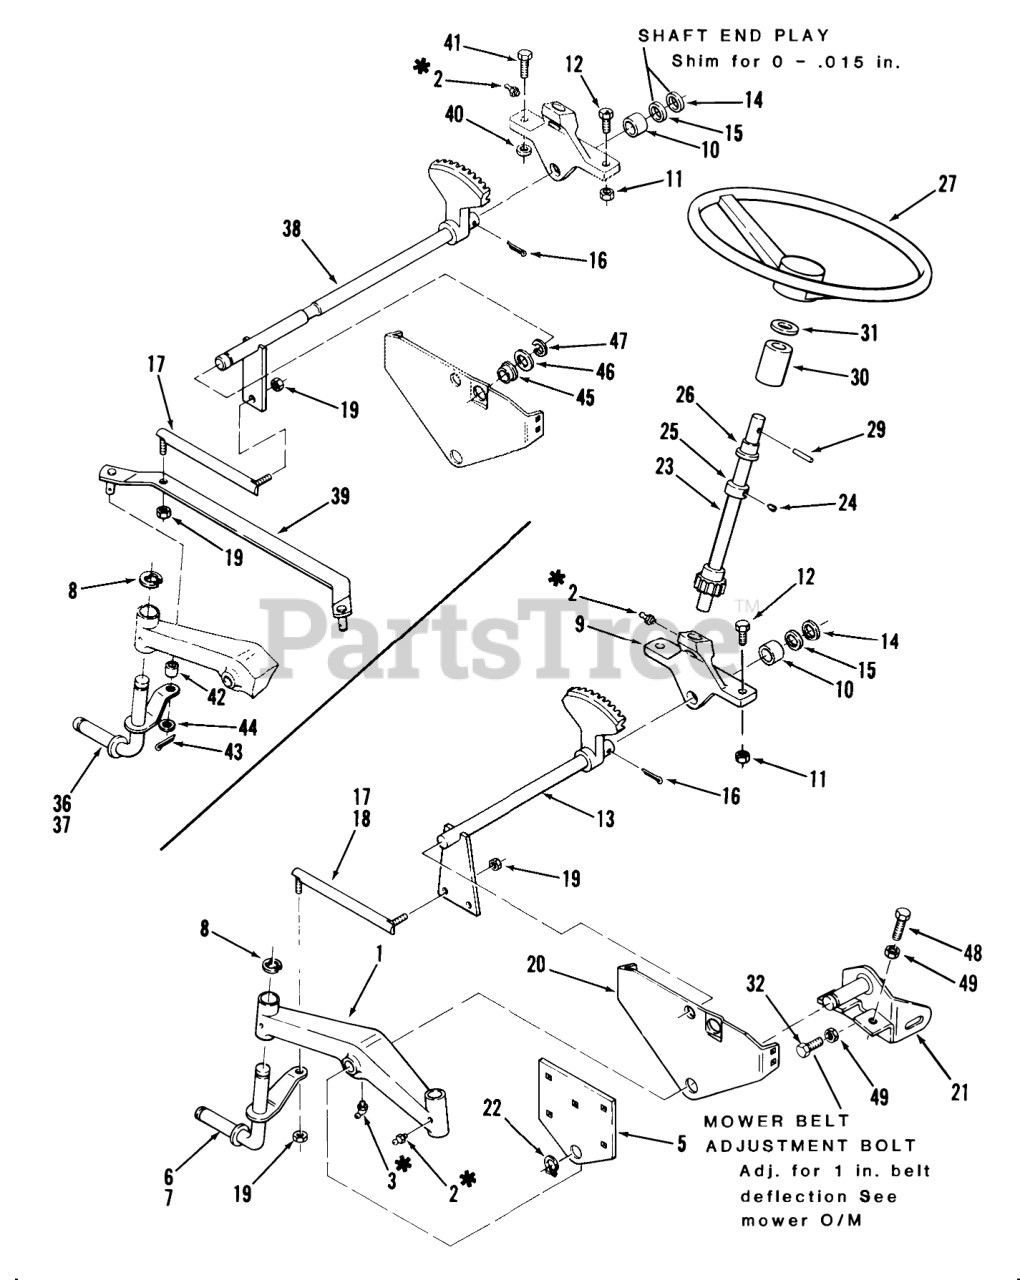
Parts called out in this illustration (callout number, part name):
1	AXLE-FRONT R
2	Zerk
3	FITTING-GREASE
5	PLATE-FRONT AXLE R
6	Assy-Front Spdl RH
7	Assy-Front Spdl LH
8	Snap Ring
9	Support
10	BEARING-BRONZE
11	Nut
12	BOLT
13	ASSY-STRG SHFT LO R
14	WASHER-SHIM
15	WASHER
16	PIN-4
17	25LL JOINT ASSY R R
18	BALL JOINT ASSY L R
19	NUT-6
20	Support Front Axle
21	ASSY-FRONT HANGER R
22	Snap Ring
23	ASSY-STEER SHFT U R
23	ASSY-STRG SHFT-UP R
24	SCREW-SET
25	Collar
26	BEARING-FLANGED
27	STEERING WH 13" PLAS
29	Pin-Roll
30	Collar 208-3 Only
30	TUBE-STEERING
31	WASHER-FLAT
32	SCREW-HH
36	Assy-Front Spdl RH B-165 Only
37	Assy-Front Spdl LH B-165 Only
38	Assy Strg Lower B-165 Only
39	ASSY-TIE ROD R
40	WASHER
41	BOLT
42	SPACER
44	WASHER
45	BUSHING
46	WASHER SPECIAL
47	Ring
48	Bolt
49	Nut
